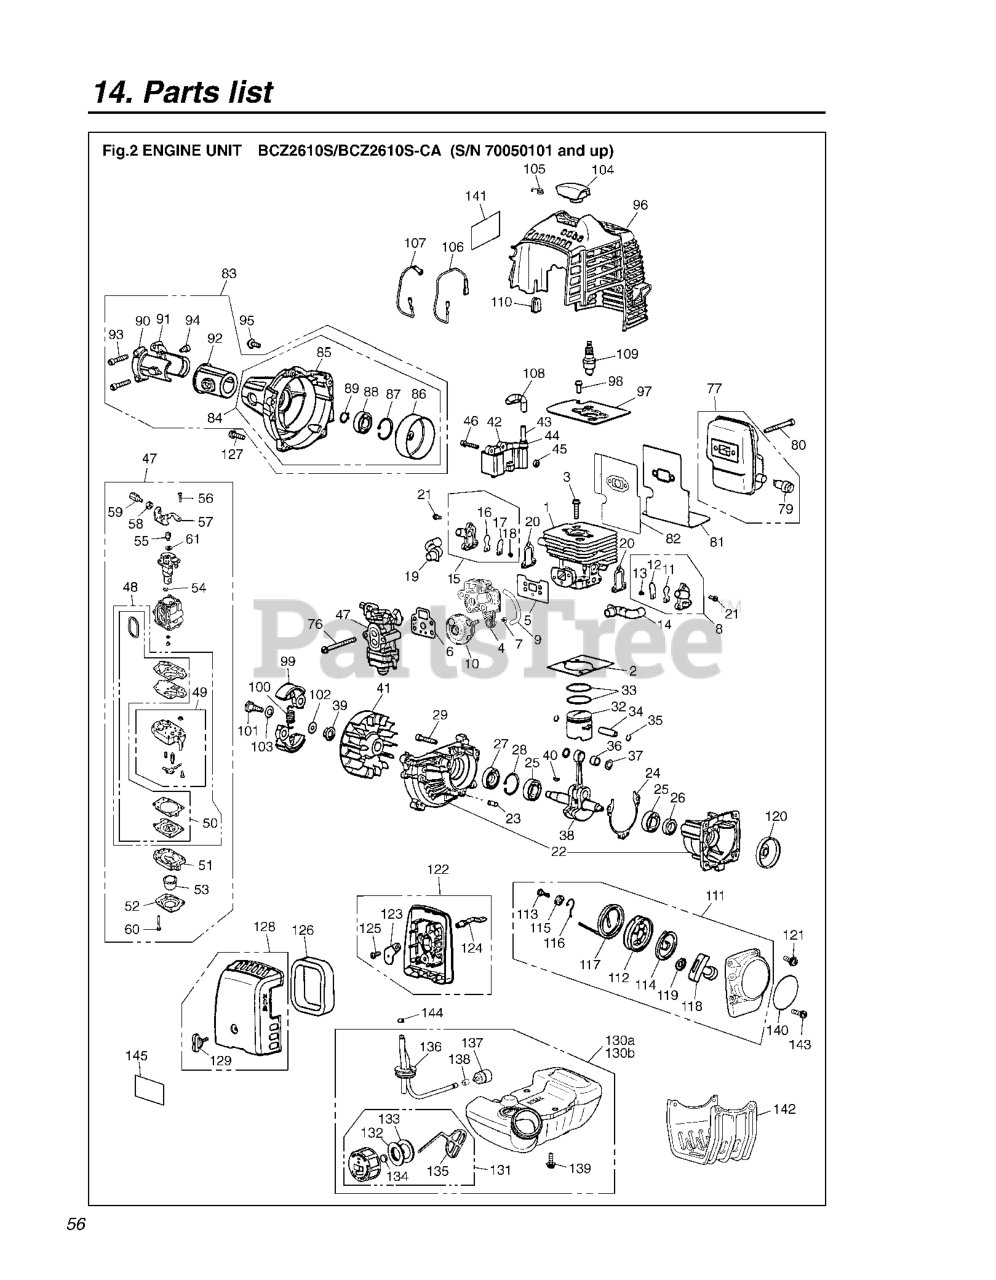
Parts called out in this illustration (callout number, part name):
1	CYLINDER
2	GASKET, BASE
3	BOLT
4	INSULATOR
5	GASKET, INSULATOR
6	GASKET, CARB (RPLS T155113131)
8	AIR CHECKER (S) ASSY
10	PUMP ASSY.
11	REEDVALVE
14	PIPE AIR (S)
15	AIR CHECKER (F) ASSY
16	REEDVALVE
19	PIPE AIR (F)
20	GASKET, VALVE
22	CRANKCASE-C
23	PIN
24	GASKET.CASE
27	SEAL
34	PIN (RPLS T151341310)
38	CRANKSHAFT COMP(RPLS481042000)
39	NUT
40	KEY
44	CAP
45	SPACER
47	CARBURETOR ASSY.
48	REBUILD KIT
49	CARBURETOR BODY
50	GASKET KIT
51	BODY CARB
52	1OVER
54	RING
55	SWIVEL
56	SCREW
57	BRACKET
58	NUT
59	ADJUSTER
61	WASHER
79	ARRESTER
82	PLATE, MUFFLER
83	COVER ASSY
84	COVER COMP. (R-31100&31101)
85	COVER.FAN
86	DRUM (RPLS 481031120-22)
88	BEARING
90	BRACKET(A)-24
91	BRACKET(B)-24
94	BOLT M5X14
96	COVER, ENGINE
107	CORD.EARTH
108	TUBE (RPLS 263072210)
109	PLUG CMR7H
111	RECOIL-A
114	SPRING, SPIRAL
115	COLLAR
116	SWING ARM
119	PLATE.STOPPER
121	BOLT M5X14
123	PLATE.CHOKE
125	SCREW
127	SCREEN
128	COVER ASSY.(RPLS 481082200)
130A	%TANK ASSY
132	HOLDER-A
136	PIPE-C
137	FILTER ASSY
138	CLIP
140	RECOIL LABEL
142	GUARD (RPLS 481031910,11)
143	BOLT
144	CLIP
